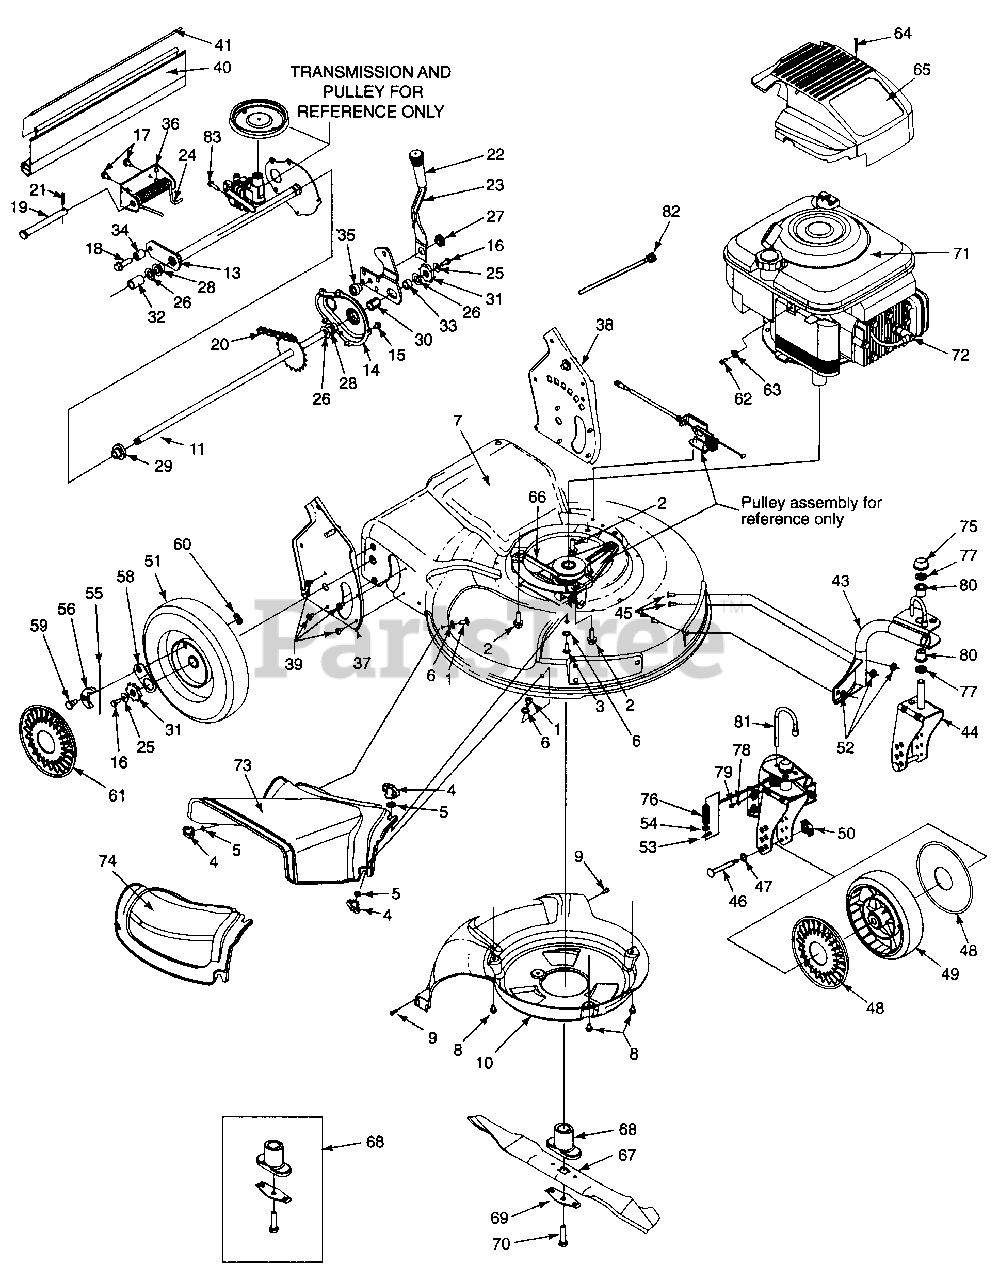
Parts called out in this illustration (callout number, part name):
1	Scr. Carr. 1/4-20 x .62
2	Scr. TT:3/8-18:1.00
3	Scr. 1/4-20 x .750
4	Wing Nut 1/4-20
5	Nut, Push .25 I.D. x .50 O.D.
6	Wash. Fl. .334 I.D. x .62 x .03
8	Scr. TT. 1/4-20 x .375
9	Scr. HL. 1/2-14 x .750
10	Baffle
11	Rear Axle Ass'y
12	Pivot Arm Ass'y
16	Cap Screw HH 1/4-20 x .620
17	Scr. AB 1/4-14 x .825
18	Scr. 3/8-16 x 1.25
19	Clevis Pin .50 Dia. x 4.82 Lg.
20	Chain-Endls. #48 .500P x 24L
21	Cotter Pin .125 O.D. x .75
23	Spring Lever
24	Torsion Spring
25	Bell Wash. .285 x .75 x .082
26	Fl. Wash. .508 I.D. 1.000 x .
27	Nut Shld. .825 Dia. x .165 Lg.
28	Hx .Flg. Brg. .506 I.D. x .590 L.
29	Hx .Flg. Brg. .506 I.D. x .715 L.
30	Hx . Slv. Brg. .504 I.D. x .830 L.
31	Wheel Rachet
32	Spa. .550 I.D. x .750 O.D.
33	Spa. .51 I.D. x .70 O.D. x 38 L.
34	Spa. .385 x .624 x .700
35	Shld. Spa. .385 I.D. x .715 Lg.
38	Handle Brkt. Ass'y. L.H.
39	Scr. AB 1/4-14 x .500
40	Trail Shield
41	Trail Shield Wire
43	Caster Ass'y R.H
43	Caster Ass'y L.H.
44	Brkt. Ass'y, Wheel Caster
45	Carr. Bolt 5/16-18 x .62
46	Caster Axle .374 Dia. x 2.50"
48	Hub Cap Whole Gray
49	Wheel 7 x 2, Caster Gray BB
50	Wing Nut 1/4-20 Thd.
51	Wheel 9 x 2 Link Gray, Sleeve
52	Lock Nut 5/16-18
53	Pin, Cotter .072 x 1.12
54	Fl. Wash. .330 x .830 x .06
55	Spring, Ratchet, Plastic
56	Pawl - L.H.
58	Ratchet Pawl Plate
59	Shld. Scr. .340 x .285
60	Top Lock Tab Weld Nut 1/4-20
61	Hubcap - Gray
62	Screw .620 Hx . Slt. Wsh.
63	Casing Clamp, Throttle
64	Scr. Hi-Lo #10 x 1.25
65	Shroud - Gray
66	Belt
67	21" Mulching Blade
68	Blade Adapter Kit
69	Blade Bell Support
70	Hex Bolt 3/8-24 x 2.5" Lg.
71	Engine
72	Spark Plug Insulator
73	Side Discharge Chute
74	Mulch Cover
76	Compression Spring
77	Fl. Wash. 5/8 O.D. x 1" O.D.
78	Fl. Wash. .203 I.D. x .403 O.D.
79	Fitting - Lube
80	Flange Bearing
83	Hex Scr. 5/16-18
